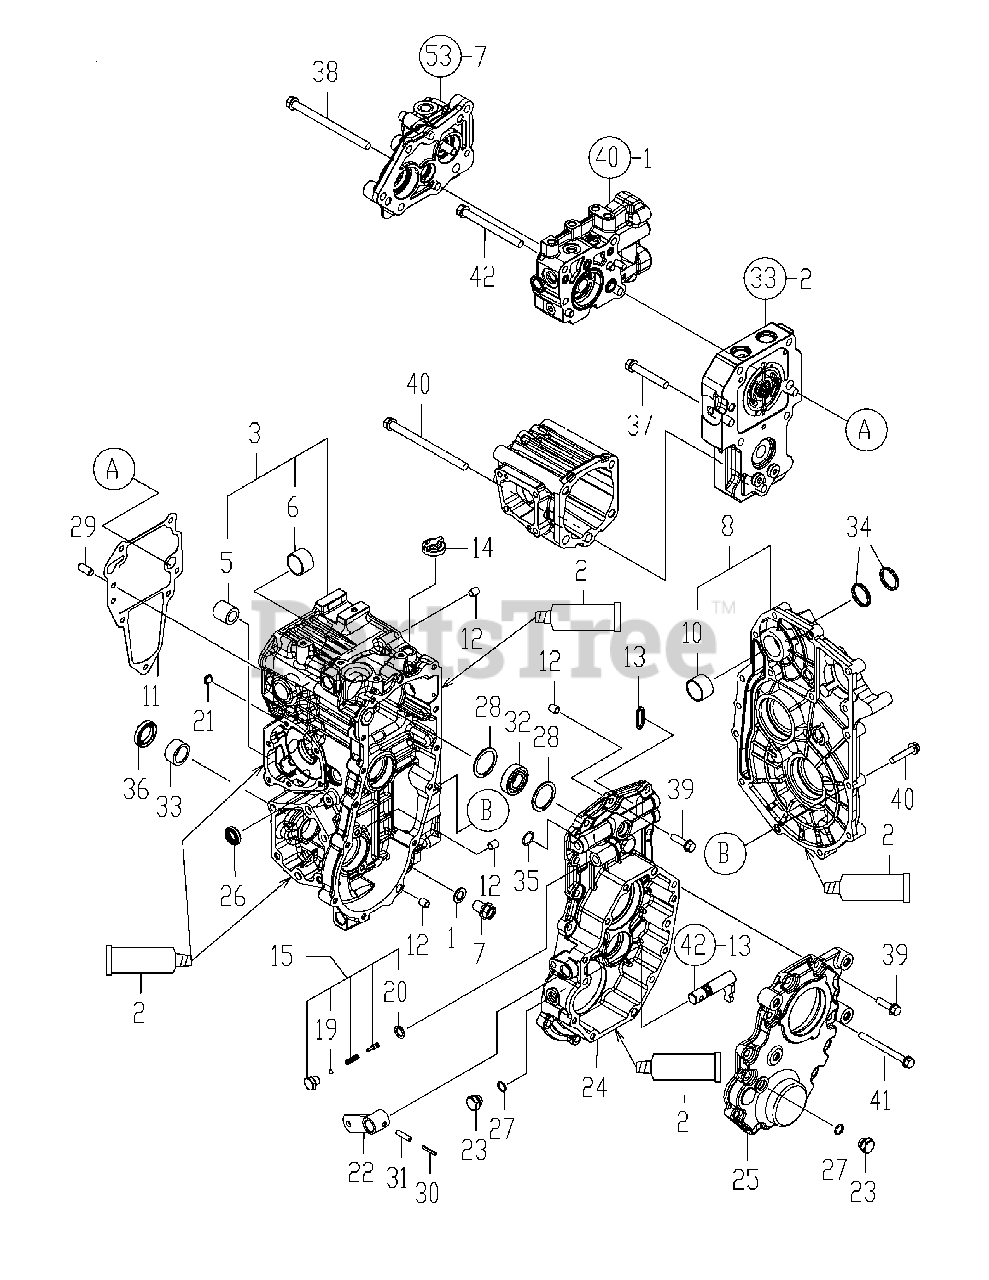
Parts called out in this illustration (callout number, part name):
2	SEALANT, TUBE
3	HOUSING KIT, MISSION
5	JOINT, STRAINER
6	BEARING, 28 X 20
7	DRAIN BOLT M14X20
8	COVER KIT, MISSION
10	BEARING, 28 X 20
11	PACKING, CENTER CASE
12	COLLAR, 8X10X11.5
14	VALVE, VENT 15
15	RELIEF KIT, PTO
20	GASKET, 12 X 1.0
23	PLUG 9/16-18UNF
24	CASE, REAR PTO
25	COVER, REAR PTO CASE
30	PIN, 3.5A X 25
31	PIN, 6.0A X 25
33	NEEDLE, 253216 NTN
34	PACKING, P 26.0
35	PACKING, 19017
36	SEAL, TC253807
38	BOLT, 10 X 145
42	BOLT, 10 X 105
